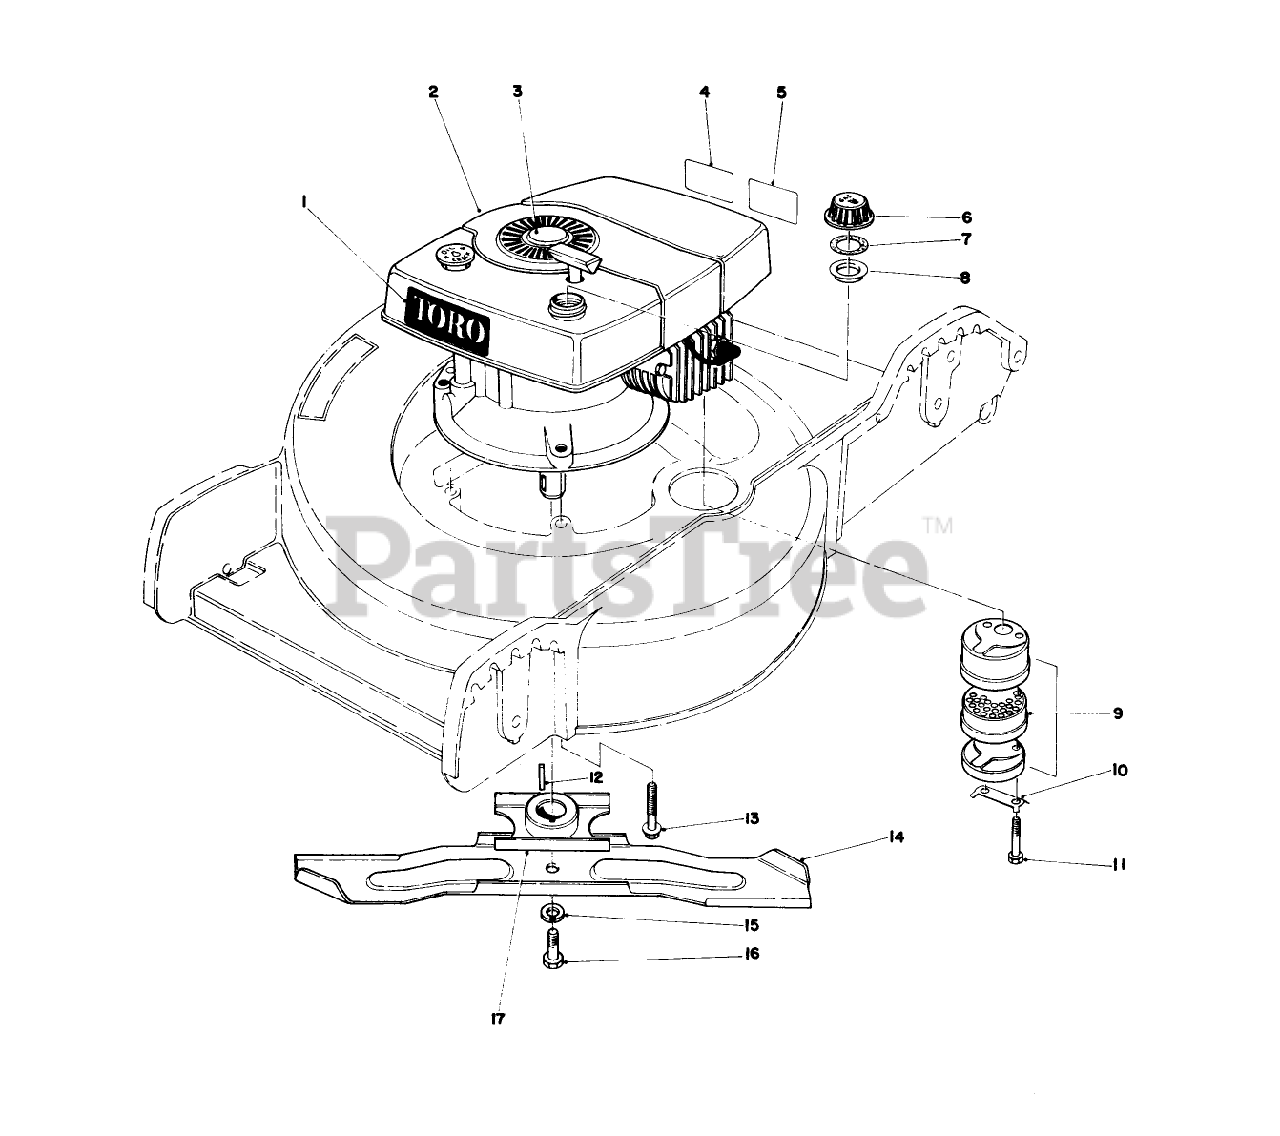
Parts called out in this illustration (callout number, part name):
2	Engine
7	GASKET
9	MUFFLER ASM
10	CLIP - LOCKING
11	SCREW-HH
12	KEY-SQUARE
13	3/8-16 X 2 CAPSCREW
15	WASHER-LOCK
